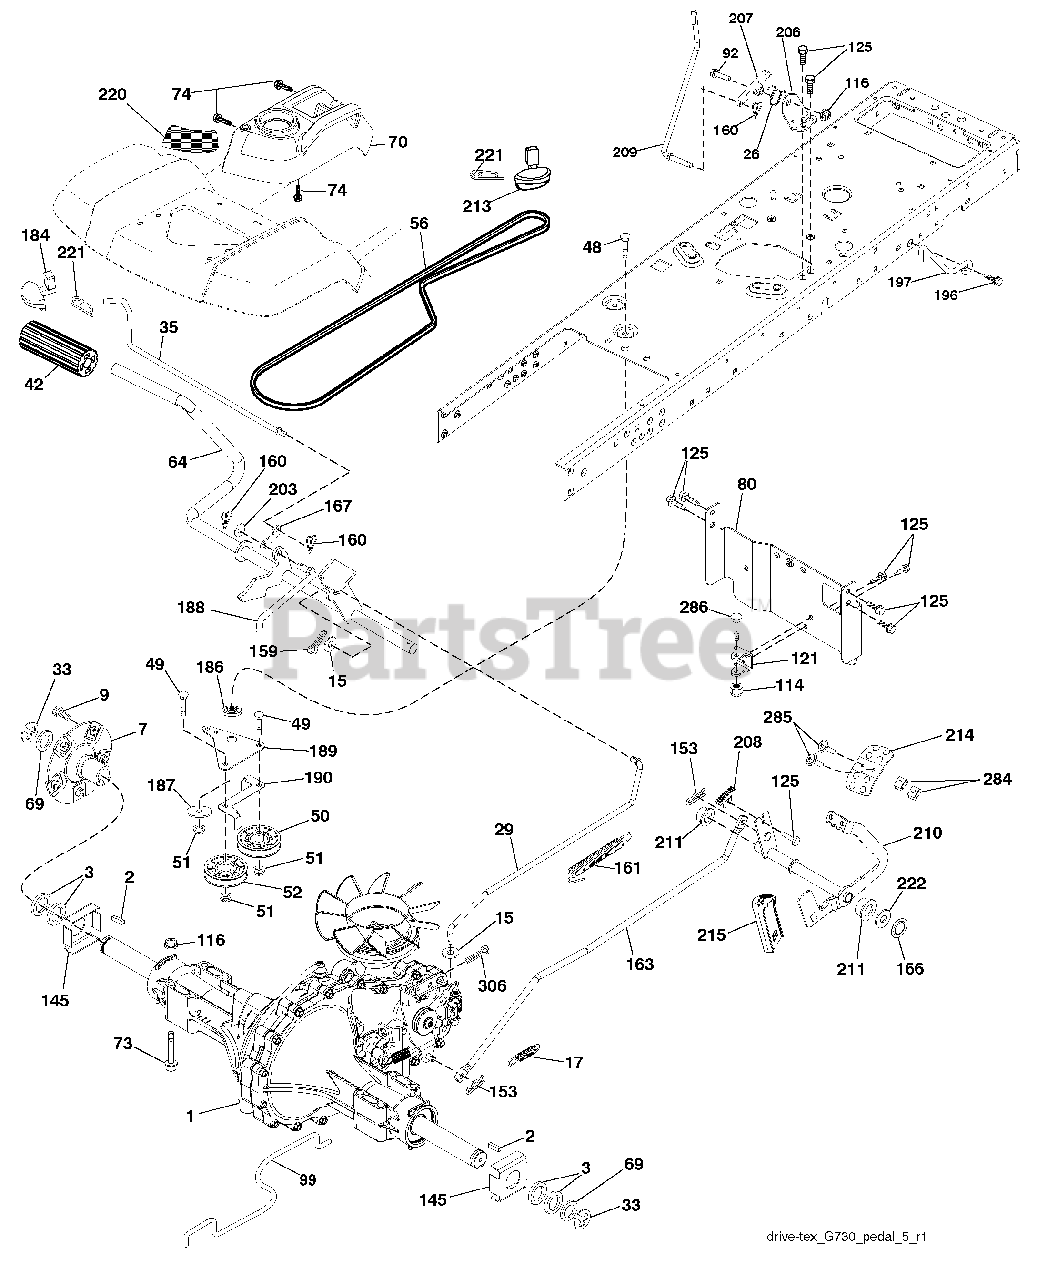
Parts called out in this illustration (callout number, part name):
2	Key 1/4 x 2.5
3	Washer Thrust Axle Hardened
7	Hub Asm. Wheel
9	Bolt Hub Wheel
15	Washer 13/32 x 13/16 x 16 Ga.
17	Spring, Brake
26	Spring Return Cruise
29	Rod, Brake
35	Rod, Brake, Park
42	Cover, Foot Pedal
48	Bolt Carr Sh 3/8-16 x 1-1/2 Gr.5
50	Pulley Idler Flat
51	Lock Nut 3/8-16
52	Idler V-Groove 910" Offset
56	V-Belt, Drive
64	Shaft Asm. Pedal Brake Control
69	Washer 1-1/32 x 1-5/8 x 16 Ga.
70	Console Asm
73	Bolt Hex 5/16-18 x 3 Gr. 5
74	Screw 1/4 x 1/2
80	Strap Torque
92	Bolt 5/16-18 x 1/2
99	Spring Bypass
114	Nut Lock Hex W/Ins. 5/16-18 unc
116	Nut Lock Hex Flange 5/16-18
121	Bracket Strap Torque
125	Screw 5/16-18 x 3/4
145	Washer Axle Flange
153	Retainer Spring
159	Pin Cotter 1/8 x 3/4
160	Retainer Clip
161	Spring, Return, Clutch
163	Rod Pedal Control
166	Nut Push .625
167	Latch Brake Parking
184	Handle Parking Brake
186	Spacer Retainer
187	Washer
188	Link Clutch Ground Drive
189	Bellcrank Ground Drive
190	Keeper Bellcrank Ground Drive
196	Screw 3/8-16 x 1
197	Bracket Clutch Anti-Rotation
203	Washer 11/32 x 11/16 x 16 Ga.
206	Bracket Mount Latch Cruise
207	Latch Control Cruise
208	Gear Sector Control Cruise
209	Rod Control Cruise
210	Rocker Asm. Pedal Control
211	Bearing Nylon
213	Knob Control Cruise
214	Pedal Forward
215	Pedal Reverse
220	Reflector RH
221	Retainer Spring Clip Handle
222	Washer 21/32 x 1-1/4 x 10 Ga.
284	Nut U-Chnl. 1/4-20
285	Screw Phd. 1/4-20 Box Drive
286	Bolt 5/16-18 x 2.50
306	Pin Cotter 1/8 x 1
